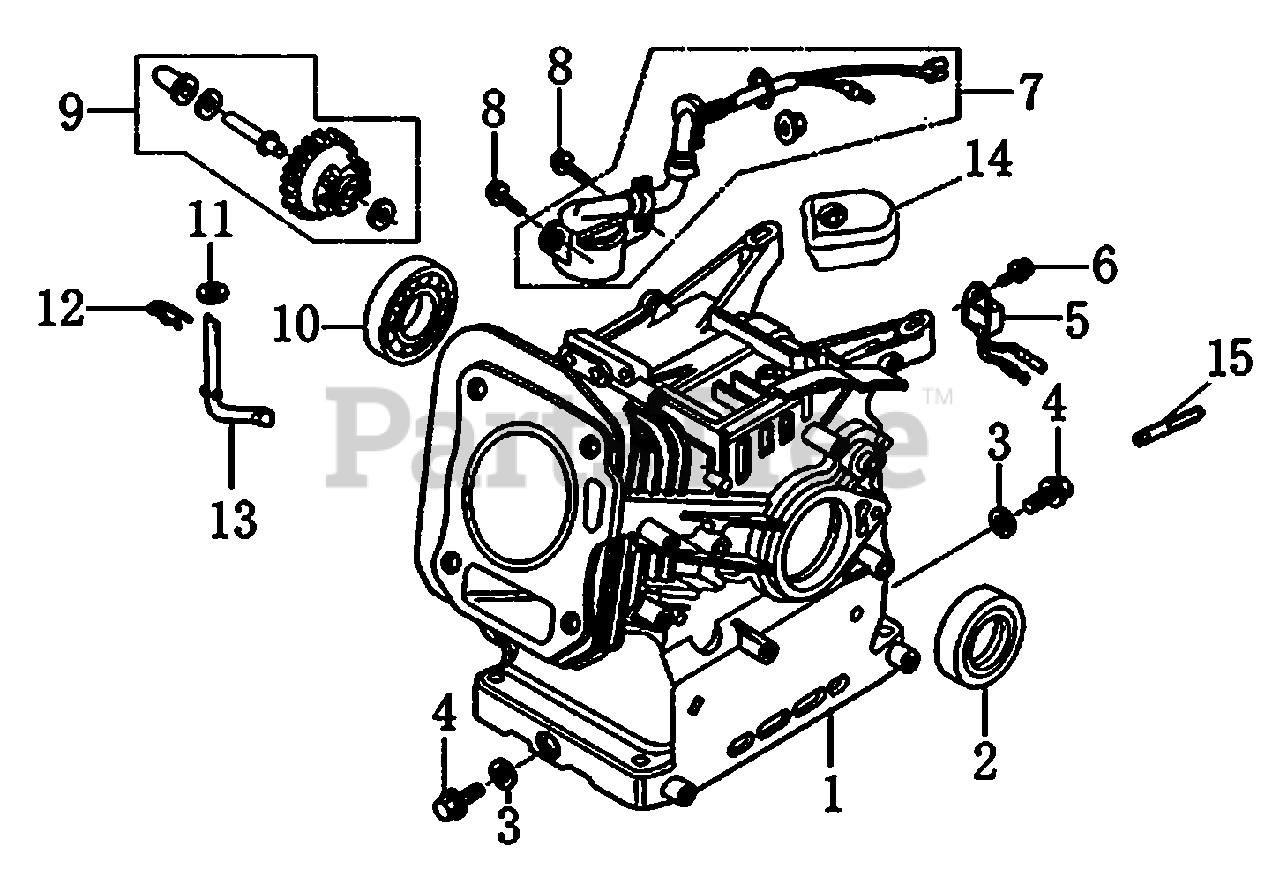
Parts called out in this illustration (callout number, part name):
1	CRANKCASE
2	SEAL, OIL 25X41.25X6
3	WASHER, DRAIN PLUG
4	BOLT, DRAIN PLUG
5	ALERT UNIT, OIL
6	BOLT, FLANGE , 6X10
7	SWITCH, OIL LEVEL
8	BOLT, FLANGE , 6X14
9	GEAR ASSY., GOVERNOR
10	BEARING , RADIAL BALL
11	WASHER, PLAIN
12	PIN, LOCK
13	SHAFT, GOVERNOR ARM
14	COVER, WIRE
15	CABLE CLEAT
